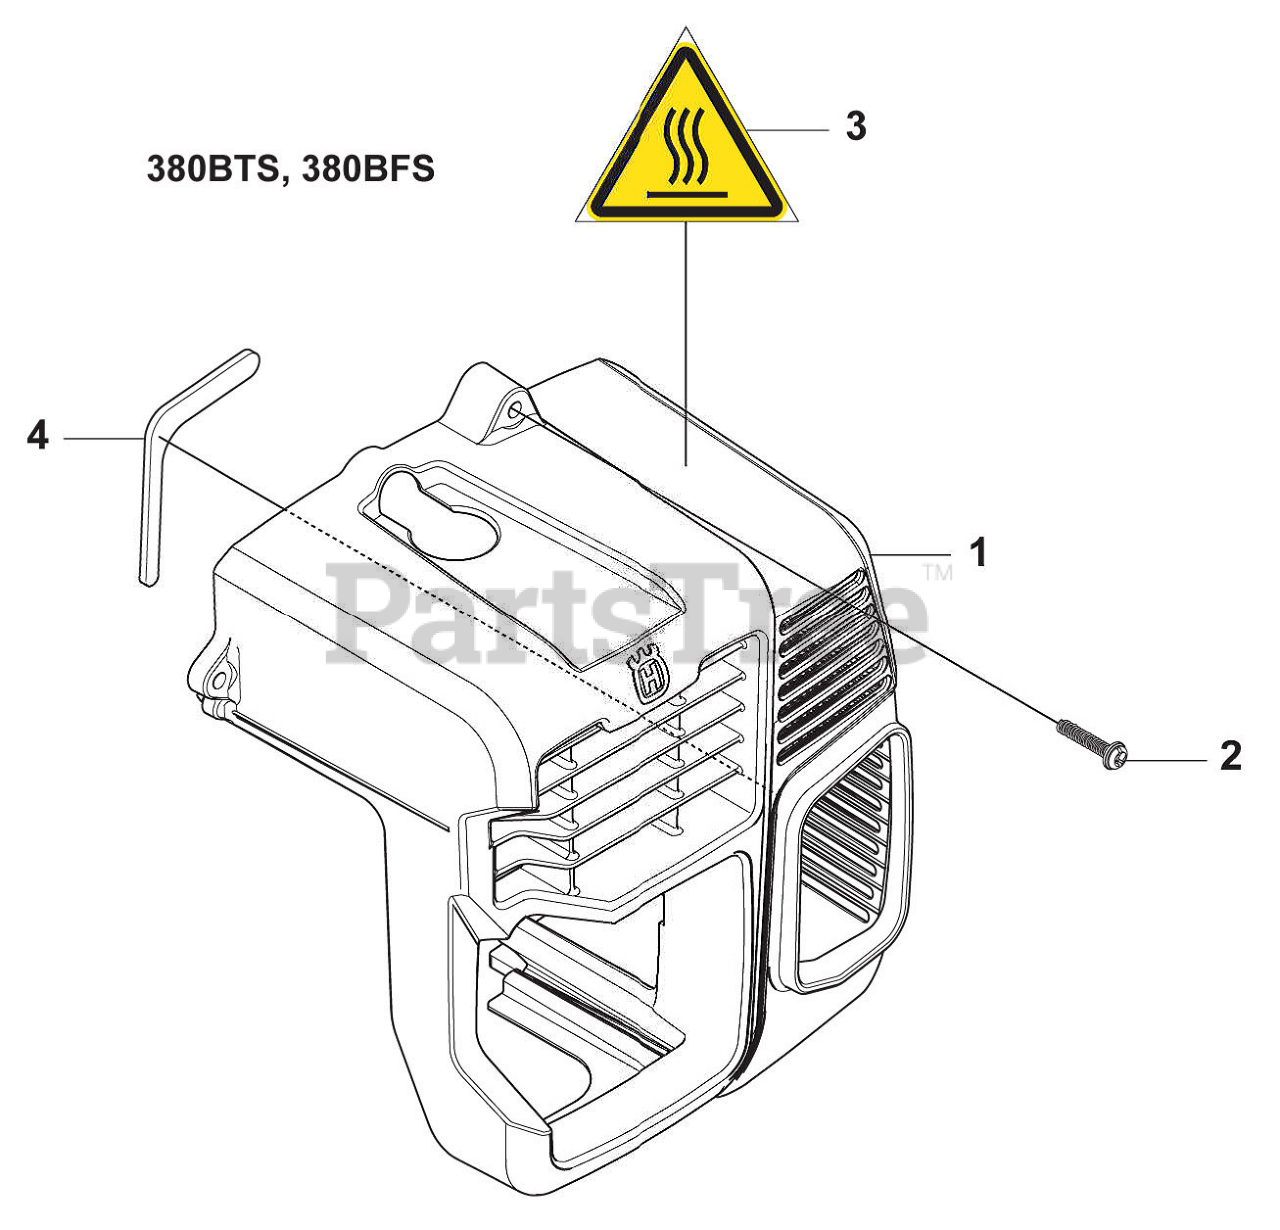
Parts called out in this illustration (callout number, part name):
1	Engine Cover
2	Screw
3	RP_LABEL, HOTMARK
